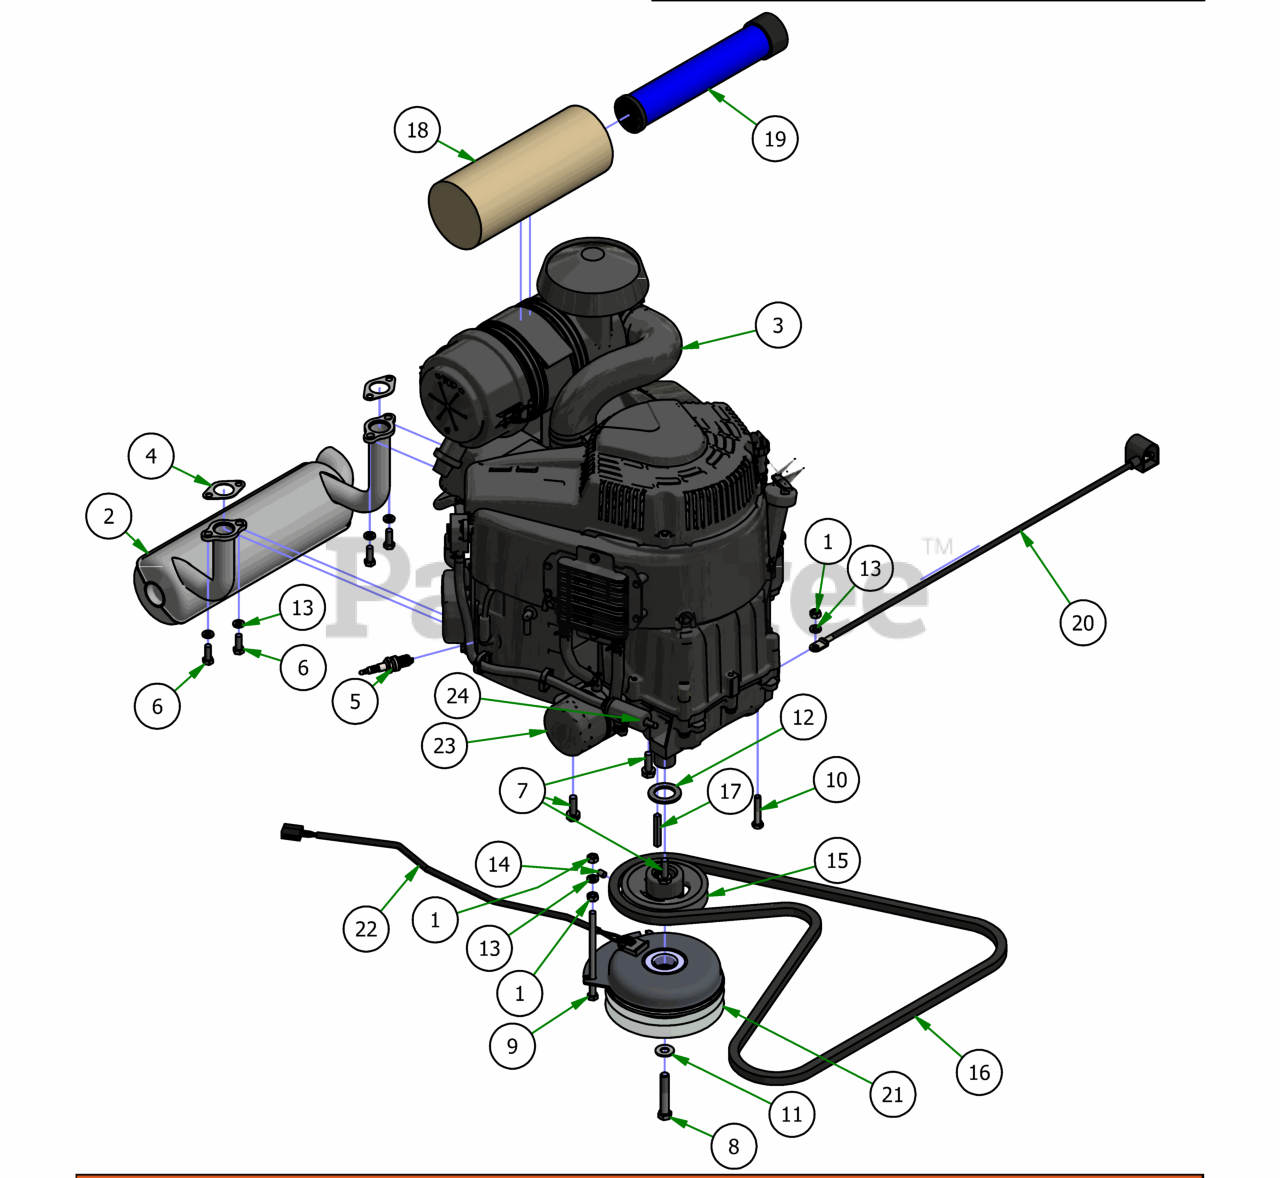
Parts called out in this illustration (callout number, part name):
2	Briggs Exhaust
3	810 Vanguard
4	Exhaust Gasket
5	Spark Plug
6	Torx Bolt-Exhaust
7	3/8 x 1 1/8 bolt
8	7/16" x 2 1/2" Hex Bolt
9	5/16-18 x 5-1/2 GR 5 Hex Bolt
10	5/16" x 1 3/4" Hex Bolt
11	3/8 FLAT WASHER USS (1" OD) ZINC
12	1 1/8" Flat Spacer
13	5/16" Lock Washer
14	3/8" Set Screw
15	4 3/4 Motor Pulley
17	1/4 x 2 Square key Stock
18	Canister Air Filter- Outer
19	Canister Air Filter- Inner
20	24 inch Black Cable – MZ/ZT
21	Clutch Assembly
22	Clutch Pigtail
23	Briggs Oil Filter
24	Universal Fuel Filter
25	Jumper Wire (Not Pictured)
